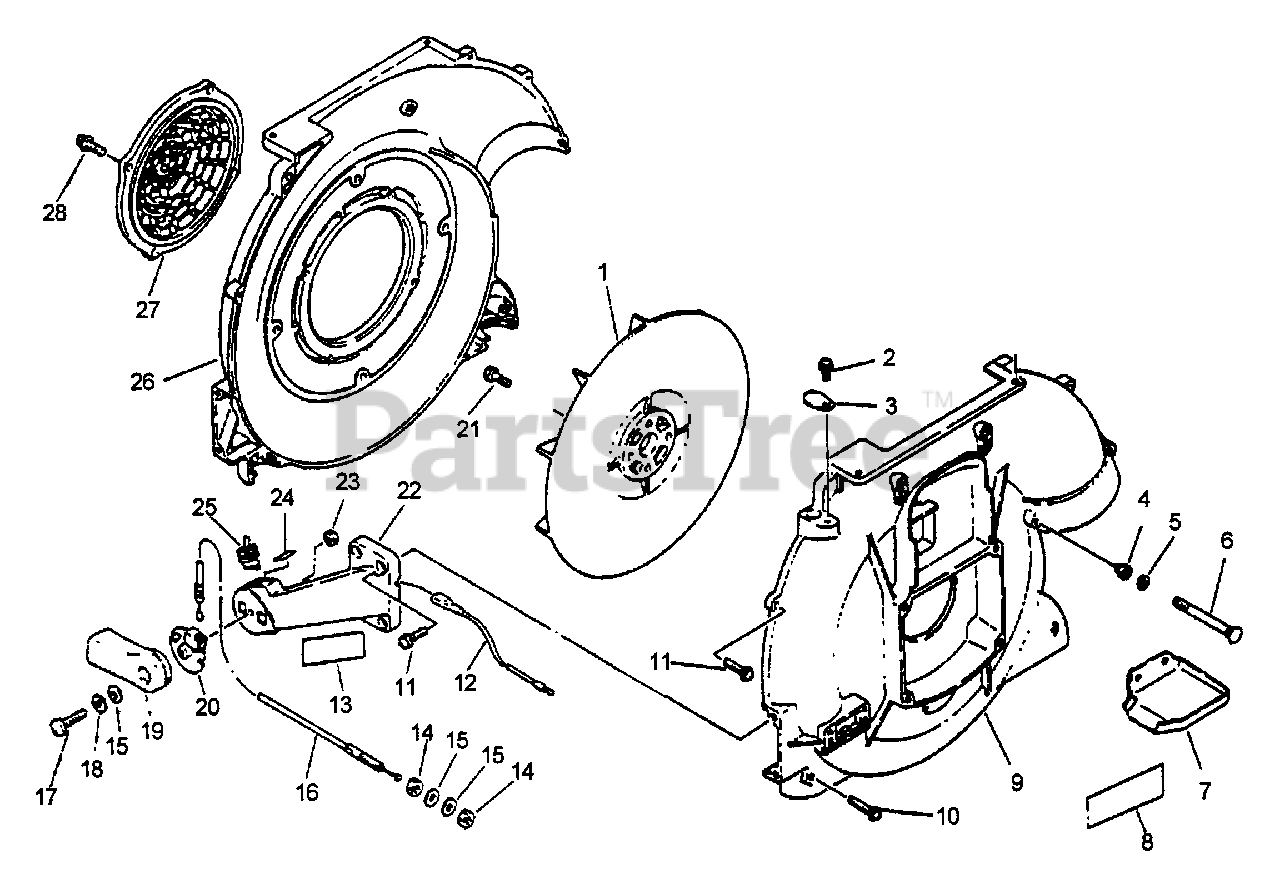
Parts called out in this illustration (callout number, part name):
2	SCREW 5×10
4	NUT - 5 -- CAP
5	WASHER, FLAT 5.5×10×0.8
7	BRACKET, MUFFLER COVER
8	LABEL - NOISE
9	COVER, FAN - OUTER
10	SCREW 5×25
11	SCREW 5×20
13	LABEL - CAUTION
16	CABLE, THROTTLE
17	SCREW 6×25
18	WASHER, SPRING 6
19	CONTROL, THROTTLE
22	MOUNT, THROTTLE LEVER
23	NUT, HEX M6
24	LABEL, ON-OFF
25	IGNITION SWITCH ASSY
26	COVER, FAN - INNER -- ORANGE
27	SHIELD, DEBRIS
